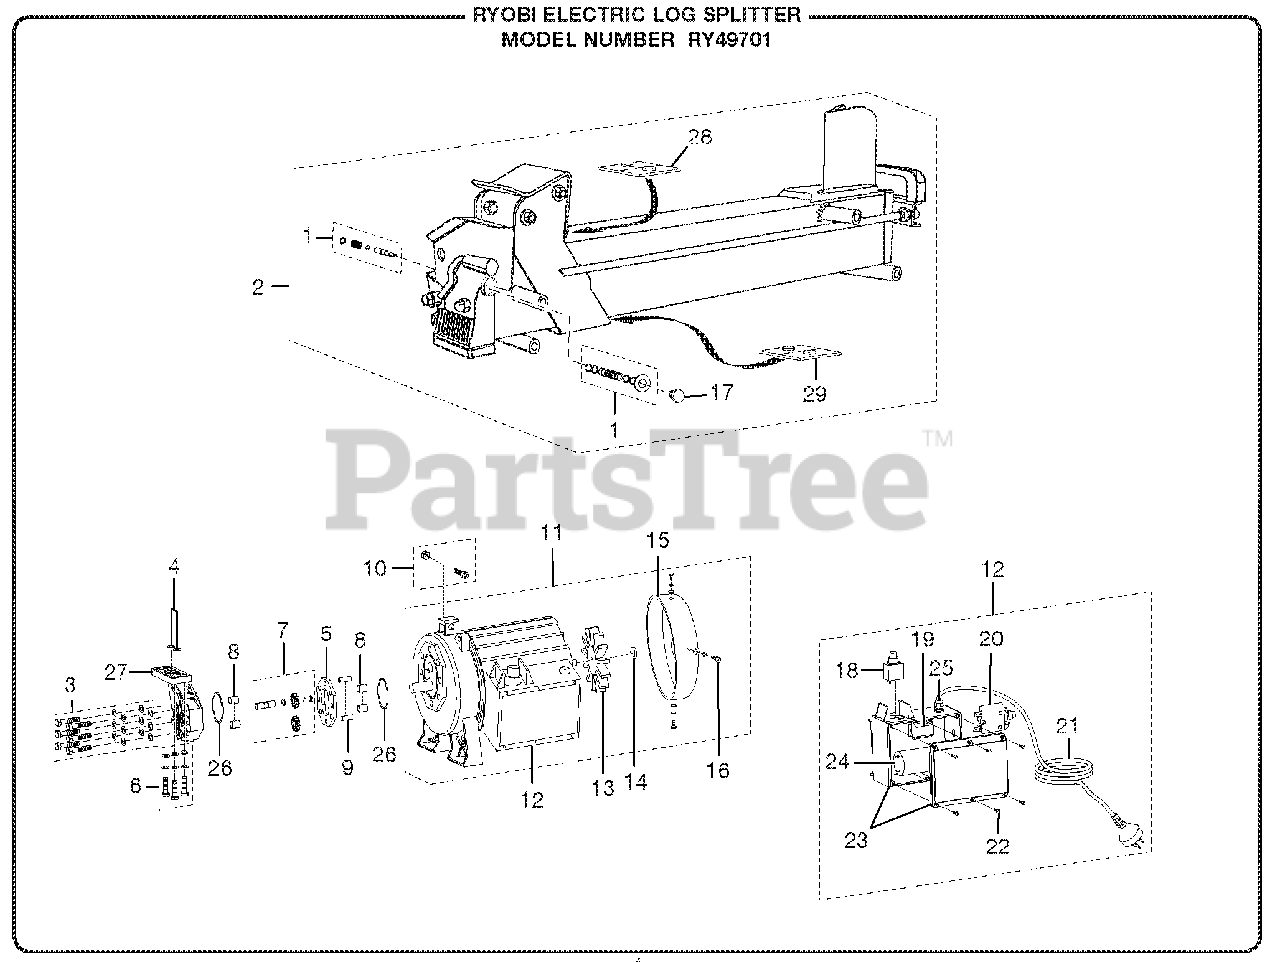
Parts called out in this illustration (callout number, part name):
1	RAM VALVE ASSEMBLY
2	MAIN BODY ASSEMBLY
3	BOLT ASSEMBLY
5	GEAR HOUSING PLATE
6	BOLT ASSEMBLY
7	GEAR ASSEMBLY
10	NUT AND BOLT ASSEMBLY
11	MOTOR ASSEMBLY
12	SWITCH BOX ASSEMBLY
14	RETAINING RING
16	SCREW (4 X 10 mm) W/WASHERS
19	CONNECTION TERMINAL
20	CIRCUIT BREAKER
22	SCREW (M2.9 X 12 mm)
23	SWITCH BOX ASSEMBLY
25	STRAIN RELIEF
27	GEAR PUMP COVER
28	UPPER WEAR PAD
29	LOWER WEAR PAD
